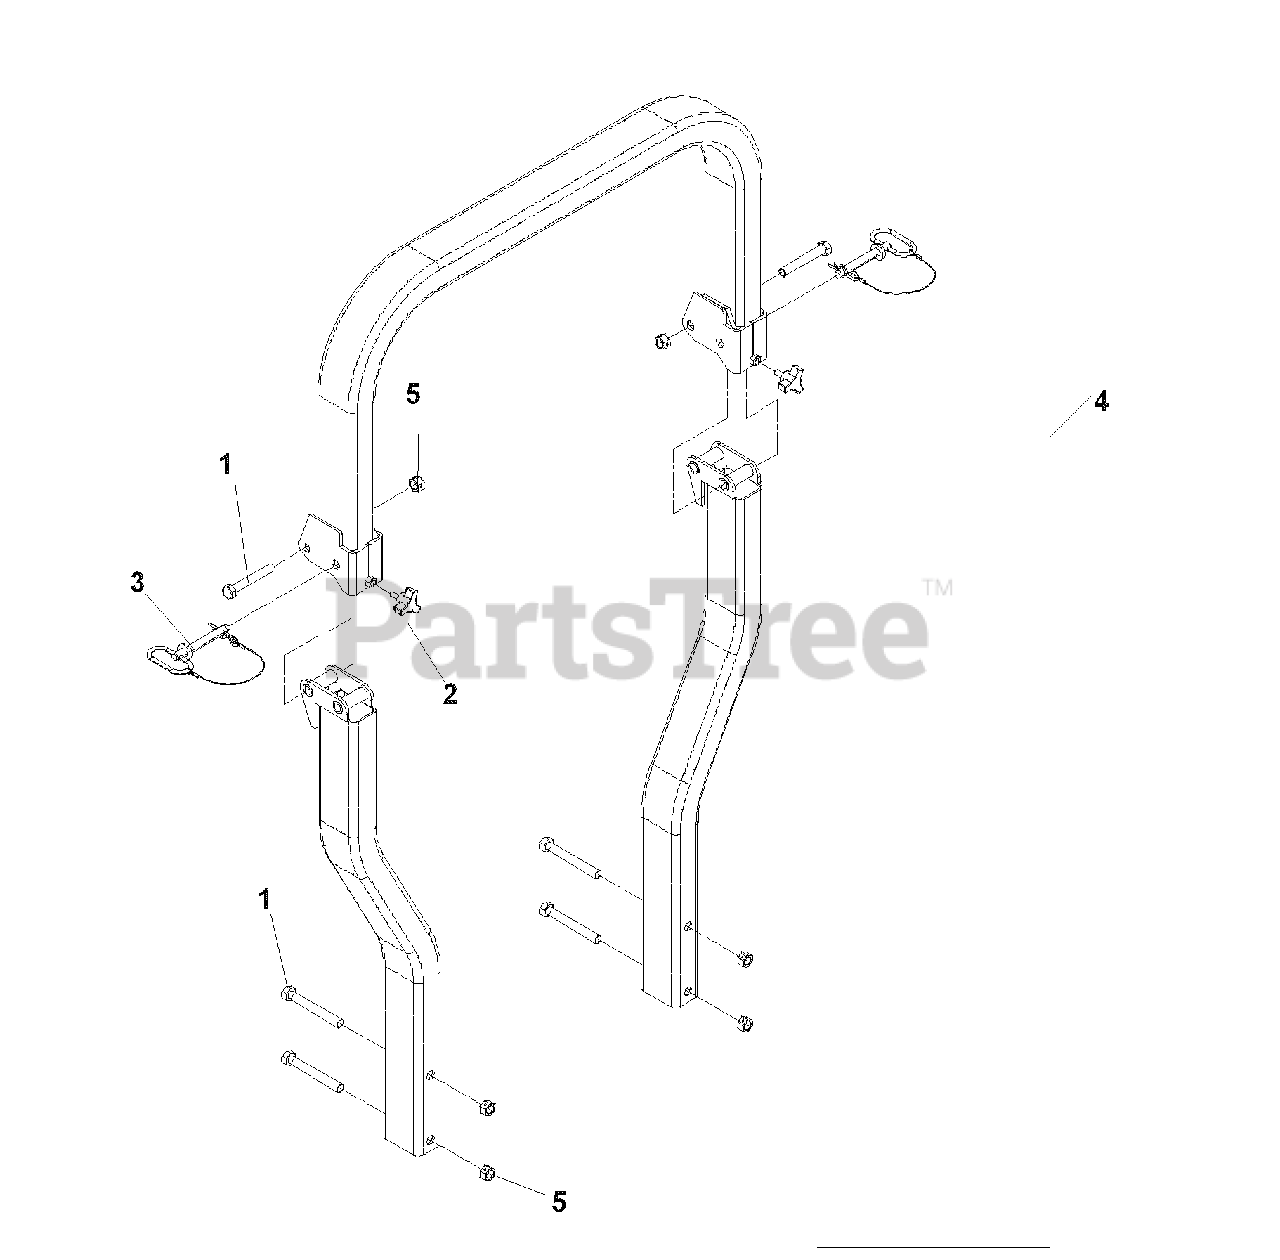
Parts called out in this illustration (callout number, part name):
1	HCS, 1/2C x 3 1/4
2	KNOB W STUD
3	LANYARD W/PIN, 1/2"
4	ROPS, COMP W/SEAT BELT
5	NUT, 1/2-13, CENTERLOCK
